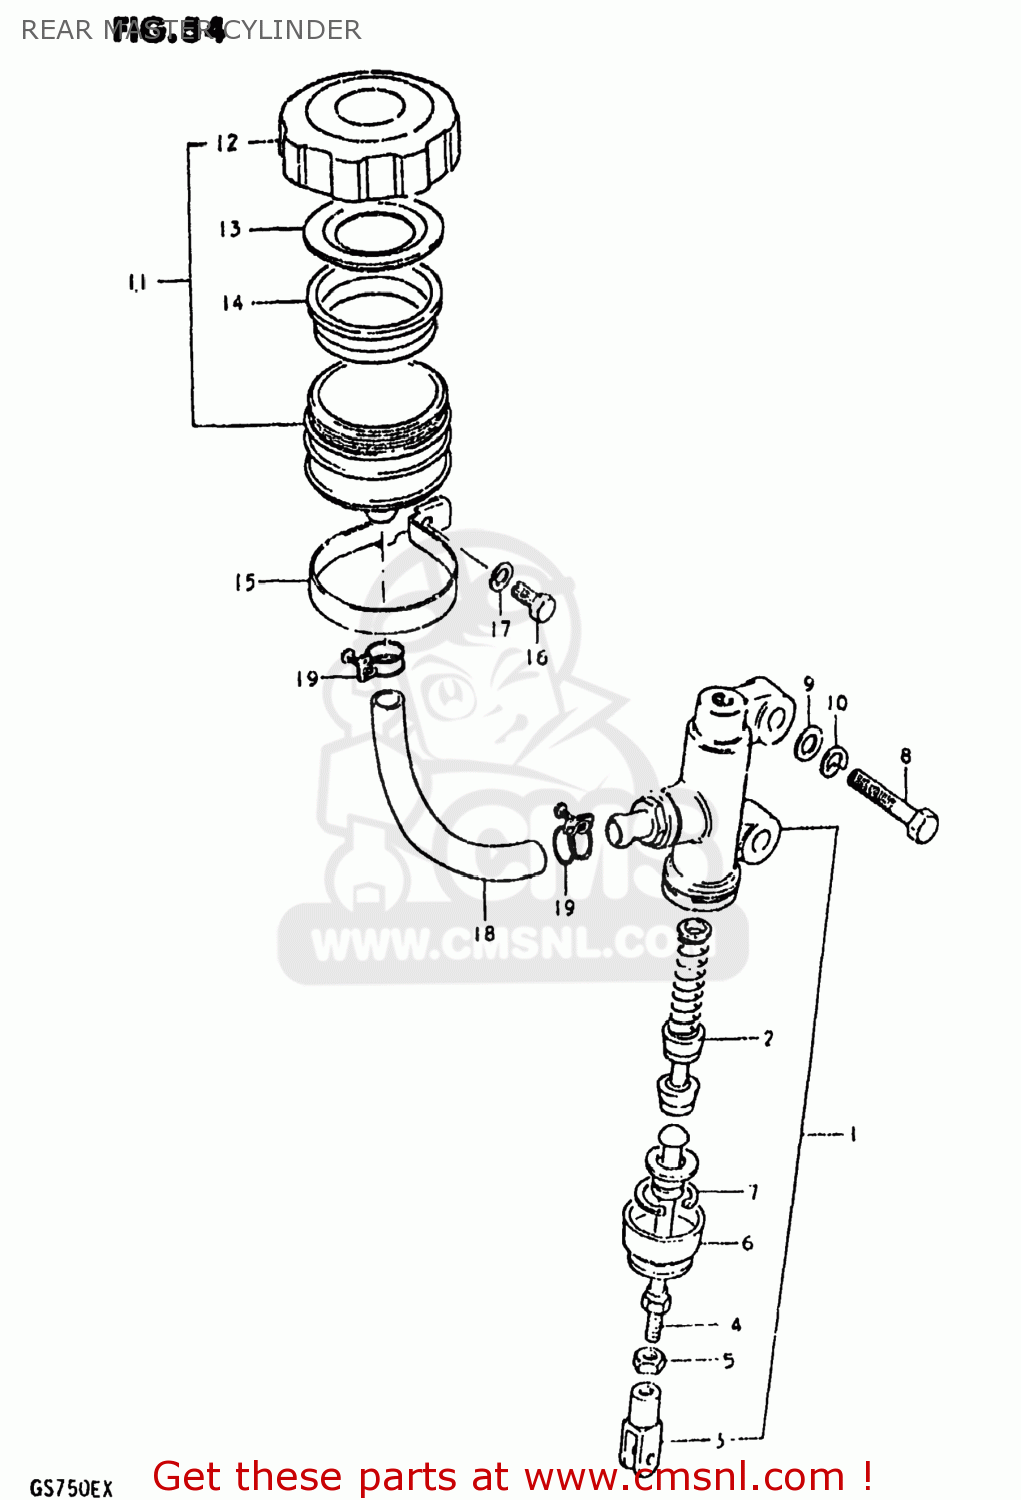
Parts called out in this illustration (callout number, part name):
1	CYLINDER ASSEMBLY,REAR MASTER
2	PISTON/CUP SET
3	YOKE
4	ROD,PUSH
5	NUT
6	BOOT
7	CIRCLIP
8	BOLT (8X30)
9	WASHER
10	LOCK WASHER
11	TANK ASSEMBLY,RESERVOIR
12	CAP
13	PLATE,DIAPHRAGM
14	DIAPHRAGM
15	CLAMP
16	BOLT, UPPER
17	LOCK WASHER
18	HOSE,RESERVOIR TANK
19	CLAMP
